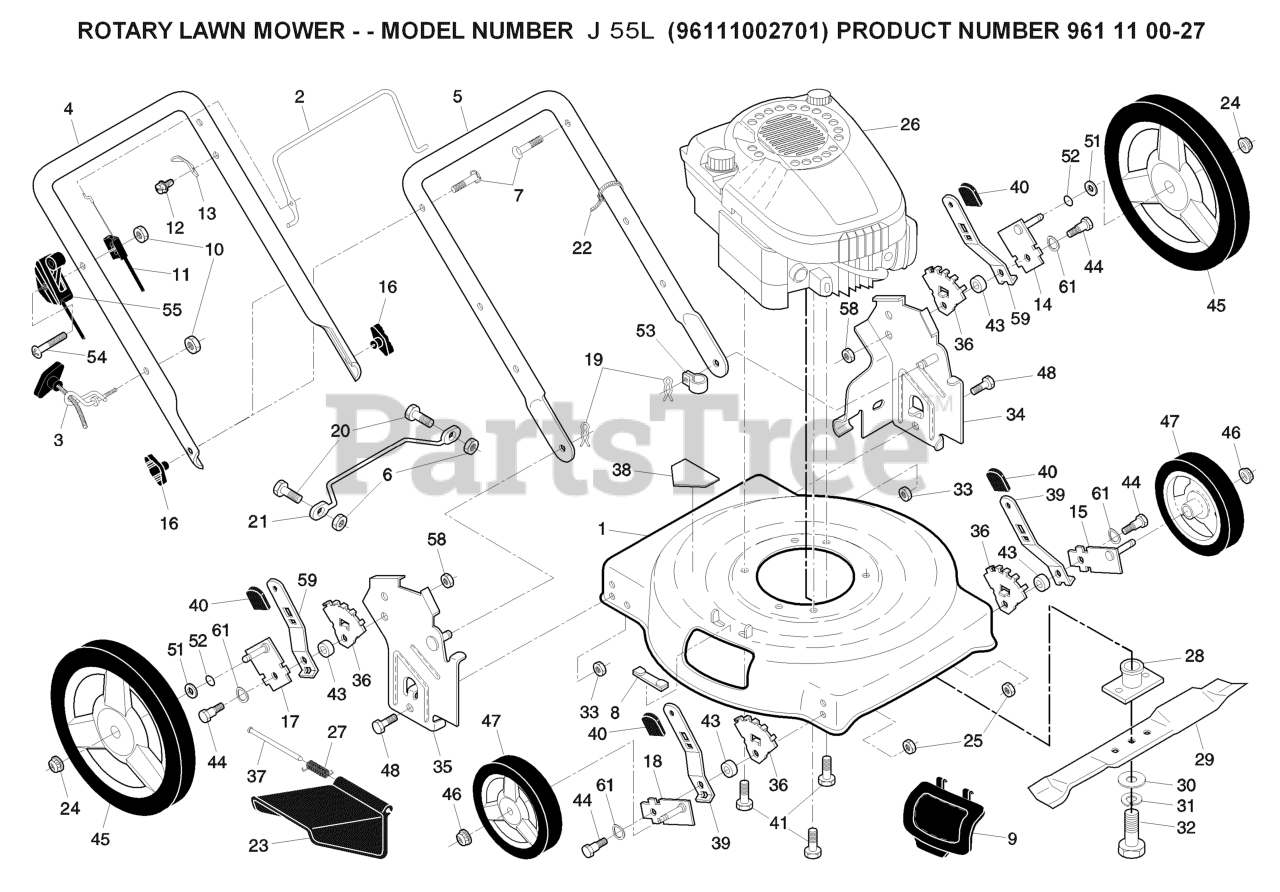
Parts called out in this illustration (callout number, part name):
1	Lawn Mower Housing
2	BAIL.MZR.STD.BLACK
3	RB GUIDE.ROPE.STD.BLK.ZIN WSL
4	Upper Handle
5	HANDLE.LOWER.GREY
7	BOLT, HANDLE 5/16-18X1.75
8	CLIP. CLOSEOUT
9	PLATE.MULCHER.22.ECON.BLACK
10	NUT
11	Engine Zone Control Cable
13	BRACKET UPSTOP
14	AXLE ARM ASSY REAR LH
15	AXLE ARM ASSY FRONT LH
16	KNOB, DEFLECTOR
17	AXLE ARM ASSY REAR RH
18	AXLE ARM ASSY FRONT RH
19	HAIRPIN COTTER
20	REPL BY 817 02 10-08
22	TIE GUIDE
23	GUARD.DISCHARGE.22".
24	NUT.HEX.FLANGE.3/8-16.LOCKNUT
25	LOCKNUT 5/16-18
27	SPRING.HINGE
28	RP BLADE ADAPTER
29	Blade, 22"
30	WASHER,HARDEN
31	LOCKWASHER
32	SCREW, HEX HD 3/8-24 X 1-3/8
33	NUT.CENTERLOCK.5/16-
34	BRACKET.ASM.HANDLE.HW.
35	BRACKET.ASM.HANDLE.HW.RT.ORANG
36	WHEEL ADJ BRACKET FRONT
38	DECAL.INTERNATIONL.CUTFINGER
39	SELECTOR SPRING, FRONT
41	BOLT 3/8-16X1-1/8
43	SPACER.HEIGHT.ADJUSTER
44	SHOULDER BOLT 5/16-18
45	RP.WHEEL.12X1.75H 3 SPOKE.RAD
46	NUT.HEX.FLANGE.3/8-16.LO(3 2)
47	WHEEL AND TIRE ASSY, REAR
48	BOLT
51	O-RING..070X.487.NEOPRENE
52	WASHER.FLAT.1/2
53	CLIP.CABLE.BLK
55	Control Throttle
58	NUT.LOCK.5/16-18
59	SPRING.SEL.EXT.21.DOMED.12/14
61	WASHER.CURVED.CYLINDRICAL
